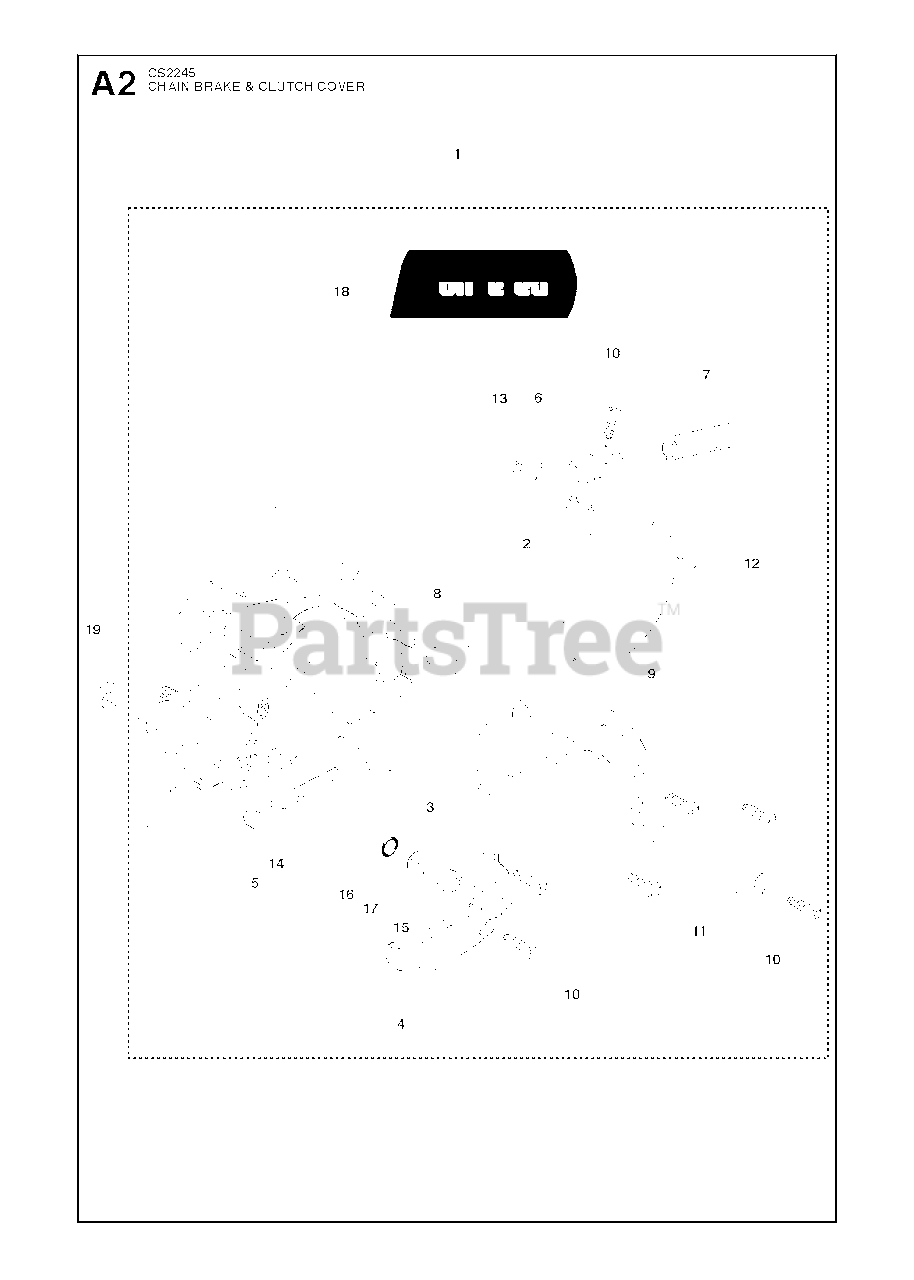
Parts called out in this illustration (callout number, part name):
1	CLUTCH COVER ASSY
2	E-RING 4
3	PAWL
4	CHAIN GUIDE
5	SLEEVE
6	JOINT
7	SPRING
8	SLEEVE
9	COVER, CHAIN BRAKE
10	SCREW
11	WEAR GUARD, CHAIN
12	BRAKE BAND
13	PIN
14	SCREW
15	SCREW
16	O-RING
17	WASHER
19	NUT M8 FLANGE
